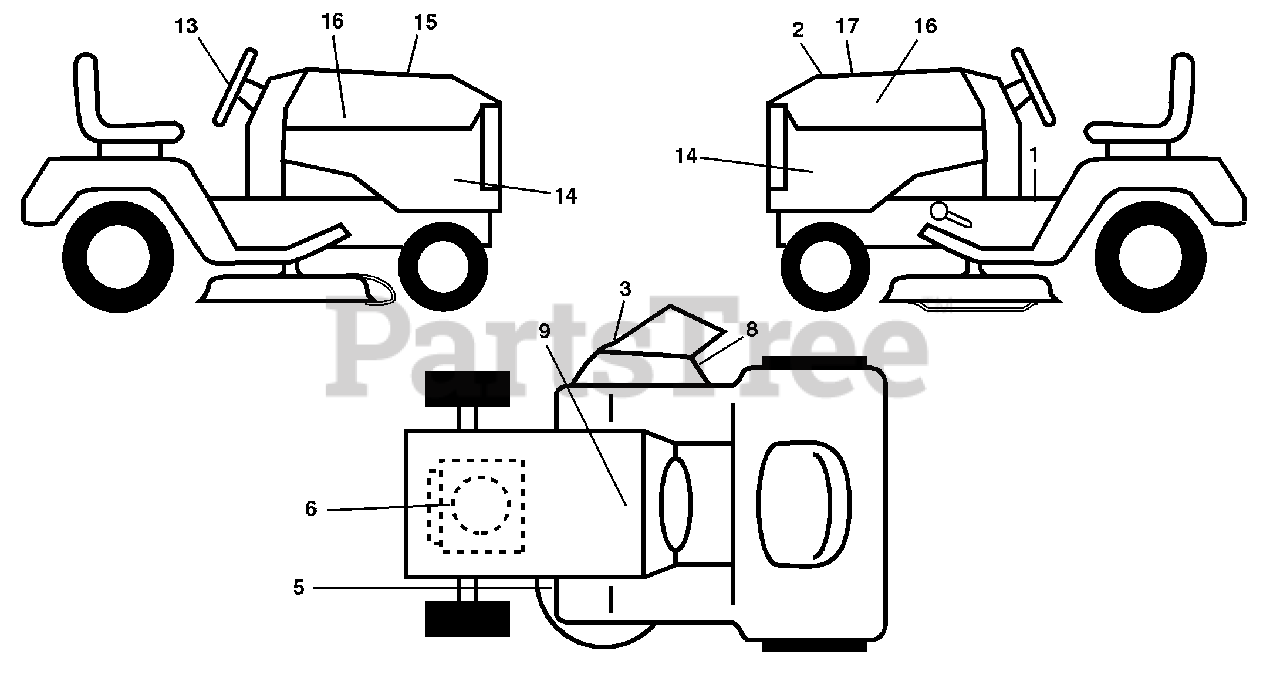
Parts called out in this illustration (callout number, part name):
1	Decal, Operator’s
2	Decal, Hood Insert
3	Decal, Warning
5	Decal, Caution
8	Decal, Mower Sch.
9	Decal, Battery Dnge/Poi
13	Decal, Steering Whl
14	Decal, Panel Side
15	Decal, Cust. Resp.
16	Decal, Hood Logo
17	Decal, Replacement
17	Decal, Bypass
17	Pad, Footrest, LH
17	Pad, Footrest, RH
17	Manual, Owner’s
